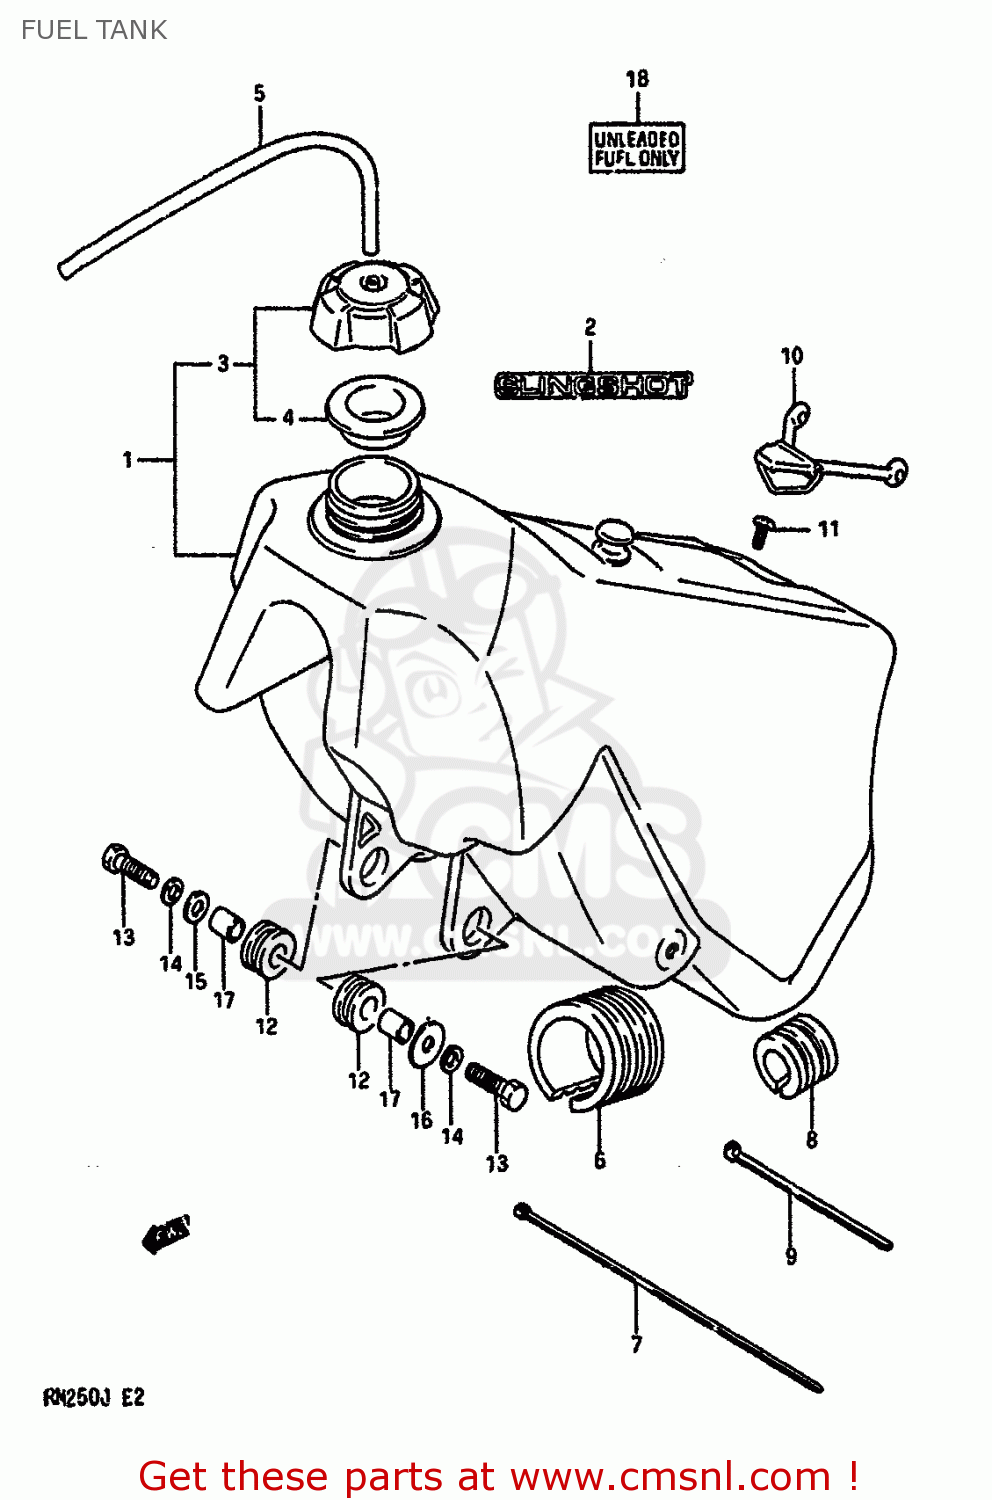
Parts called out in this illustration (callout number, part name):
1	TANK SET,FUEL
2	EMBLEM
3	CAP SET,FUEL TANK
4	GASKET,FUEL TANK CAP (NAS)
5	HOSE
6	CUSHION,FUEL TANK NO.1
7	CLAMP
8	CUSHION,FUEL TANK NO.2
9	CLAMP(L:145)
10	BAND,FUEL TANK RR
11	SCREW
12	CUSHION
13	BOLT
14	LOCK WASHER
15	WASHER
16	WASHER(8.5X26X1.2)
17	SPACER(8.4X12X12)
18	LABEL,UNLEADED FUEL
